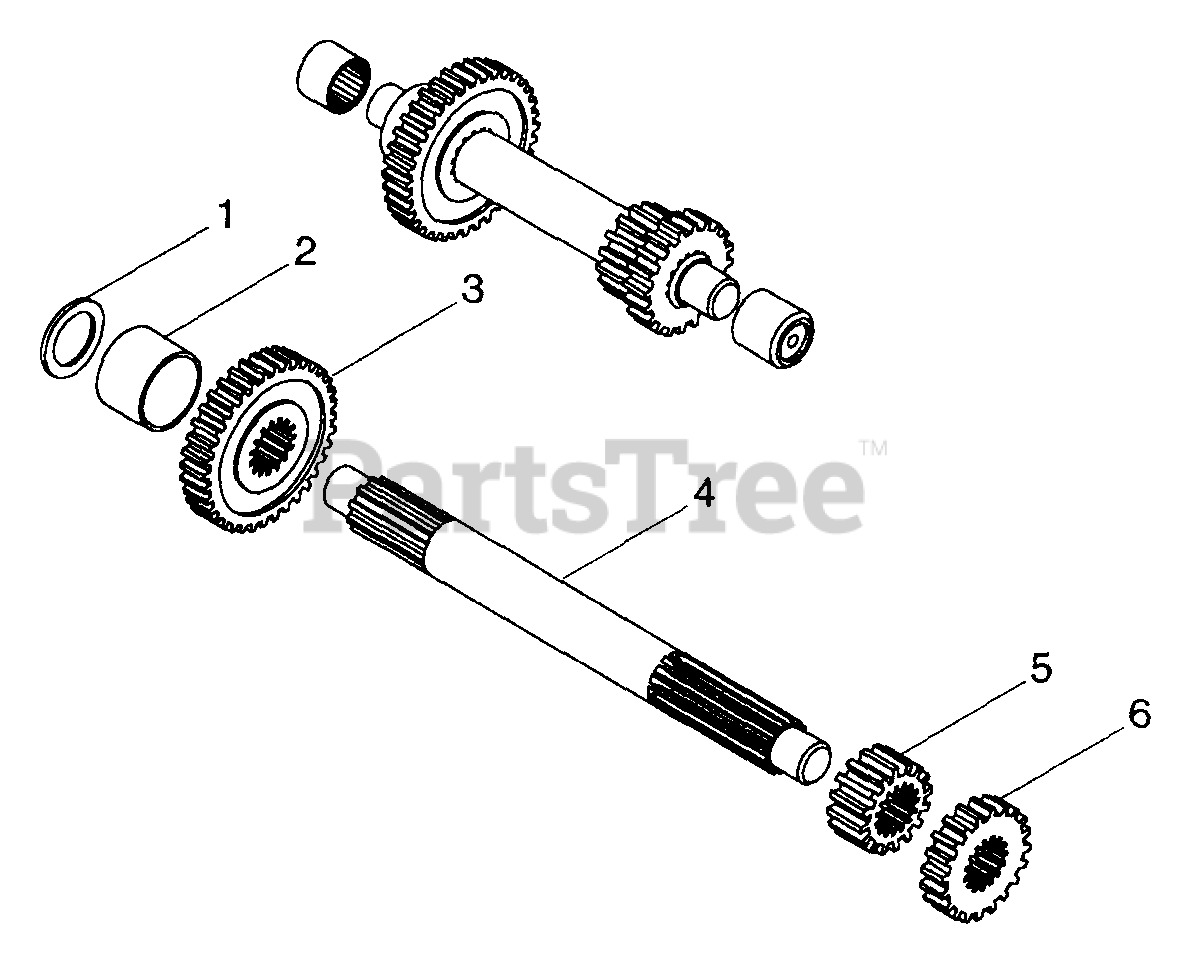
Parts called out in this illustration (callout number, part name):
1	Washer-Thrust .63 x 1.15 x .093
2	Bushing-Sleeve 1.03 x 1.13 x .457
3	Gear
4	Shaft, Splined
5	Gear, 10 DP 16 Teeth x .750
6	Gear, 10 DP 20 Teeth x .600
